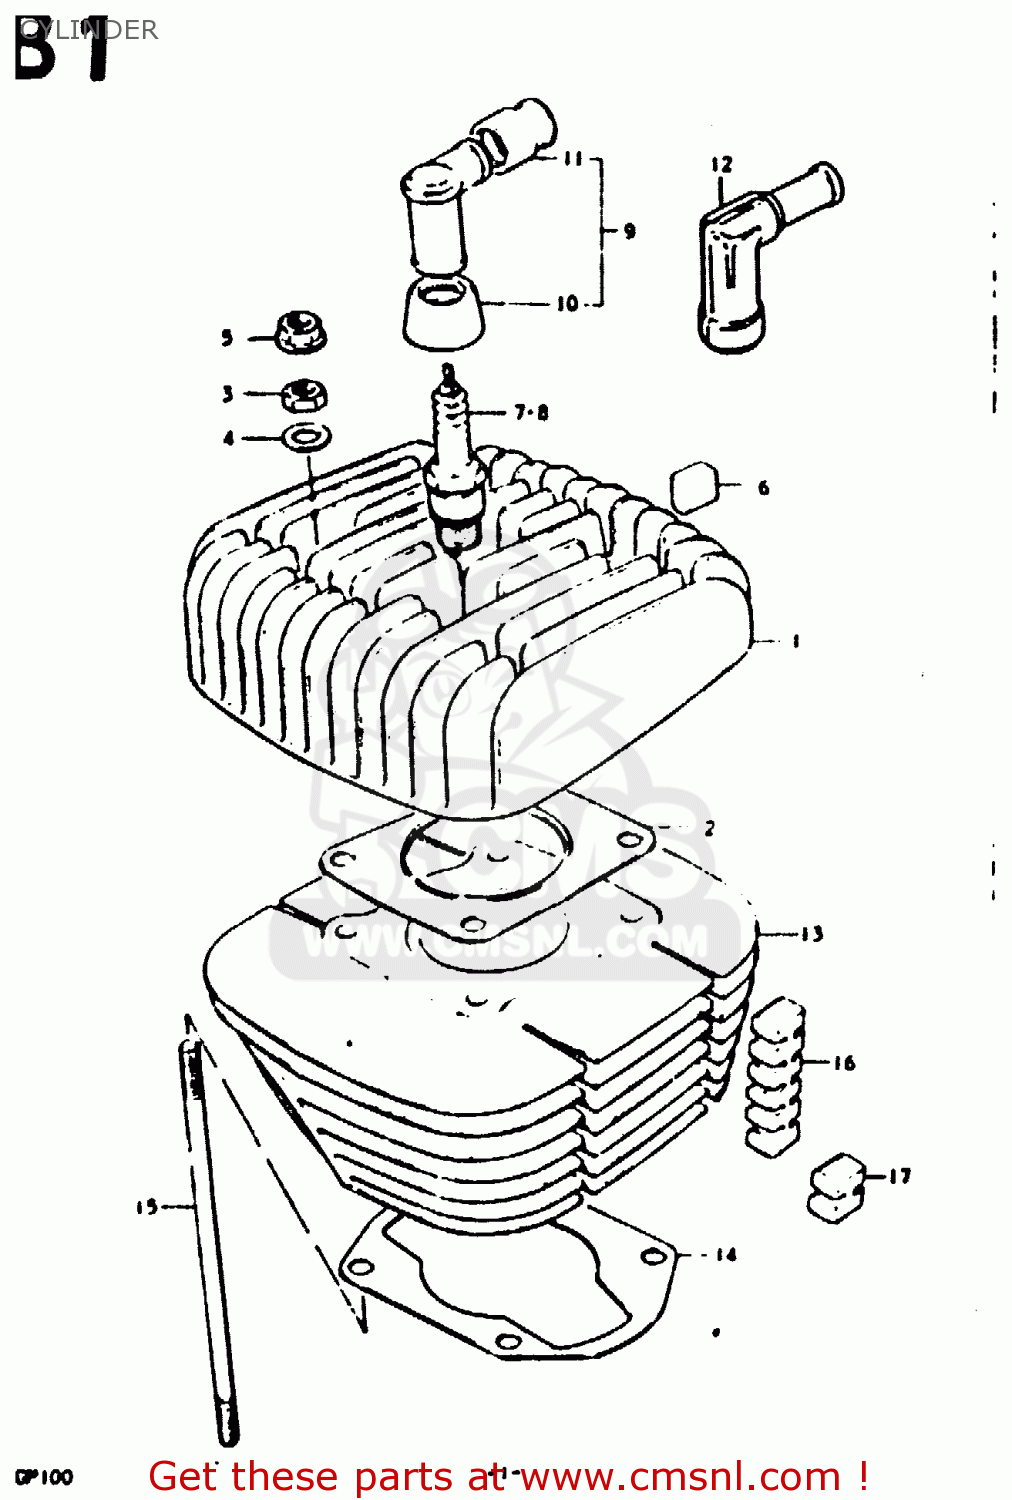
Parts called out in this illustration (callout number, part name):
1	HEAD,CYLINDER
2	GASKET, CYLINDER HEAD (MCA)
5	NUT
6	PAD,CYLINDER
7	PLUG,SPARK(B8HS)
8	SPARK PLUG
12	CAP,SPARK PLUG
13	CYLINDER
14	GASKET, CYLINDER (MCA)
15	BOLT,STUD
16	RUBBER PAD, CYLINDER (1)
17	PAD,CYLINDER
